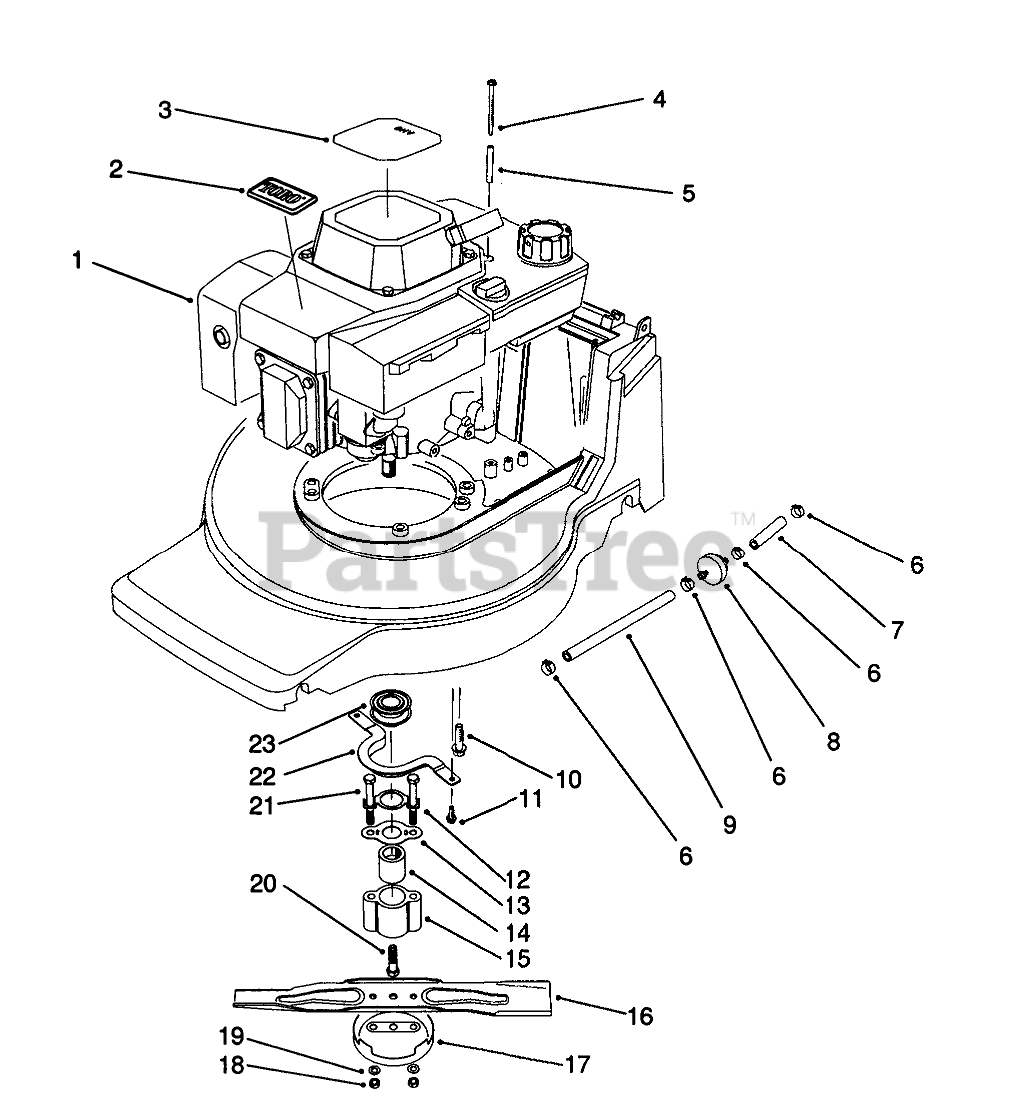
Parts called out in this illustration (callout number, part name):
1	Engine-OHV
2	TORO LOGO PLT
3	DECAL-HV INT'L
4	THRD FORMING SCREW
5	TUBULAR SPACER
6	CLAMP-FUEL LINE
7	LINE-GAS
8	FILTER-FUEL
9	HOSE-FUEL
10	SCREW-HWHTF
11	SCREW-HWH
12	BLADE RETAINER BRKT
13	SPRING FRICTION
15	RETAINER
16	Blade-48cm
17	CUP-SCALP, ANTI
18	NUT-LOCK
19	WASHER
20	SCREW - CRANKSHAFT
21	SCREW - BLADE
22	Guide-Belt
23	PULLEY-DRIVE, ZONE START
